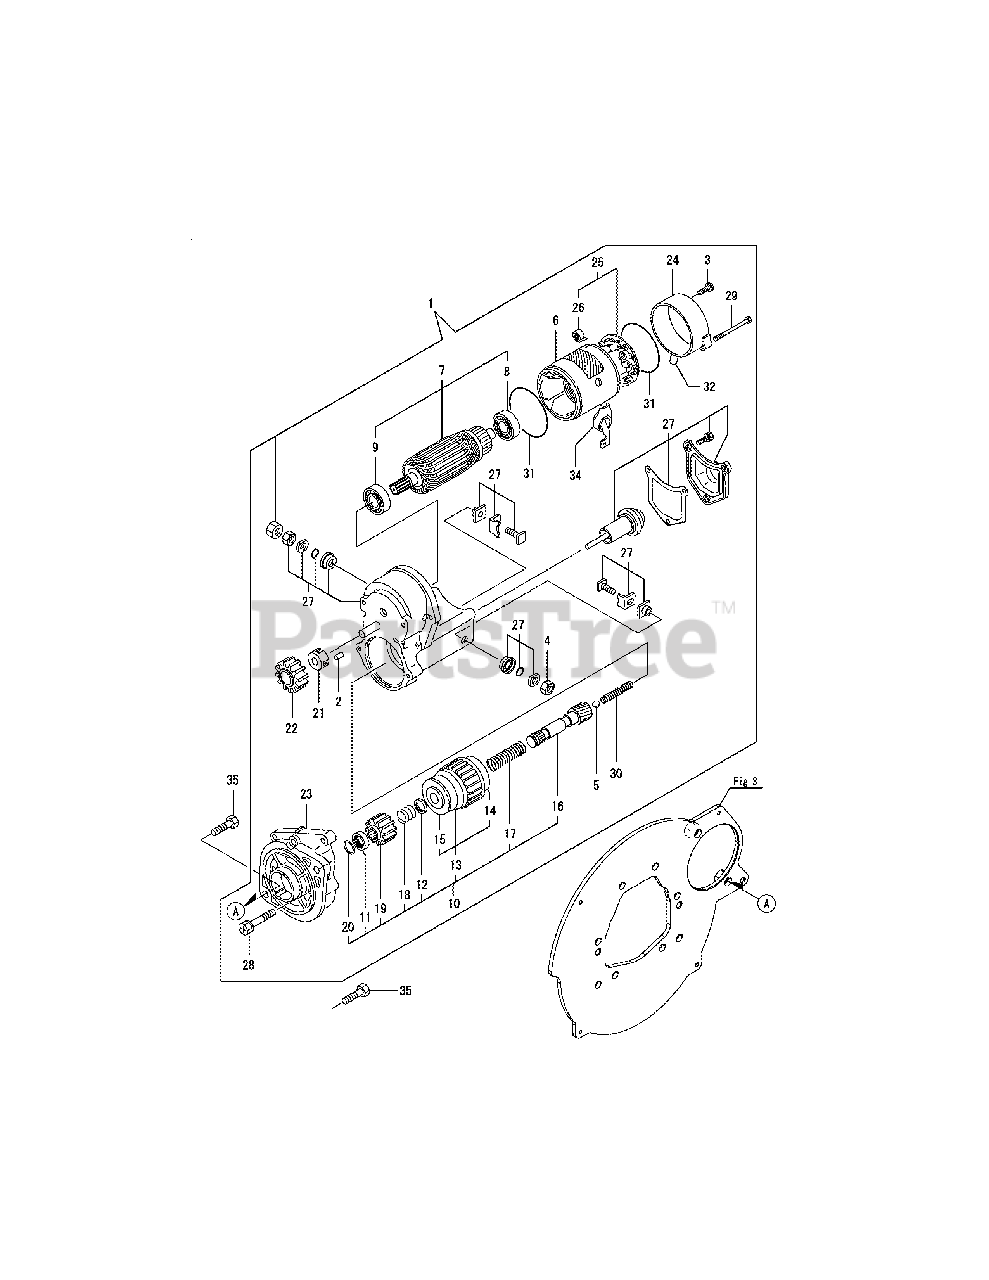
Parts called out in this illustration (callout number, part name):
1	STARTER, RA1.2
10	CLUTCH SUB-ASSY
12	RETAINER, SNAP
13	CLUTCH ASSY, STARTER
35	BOLT M12X 30 PLATED
